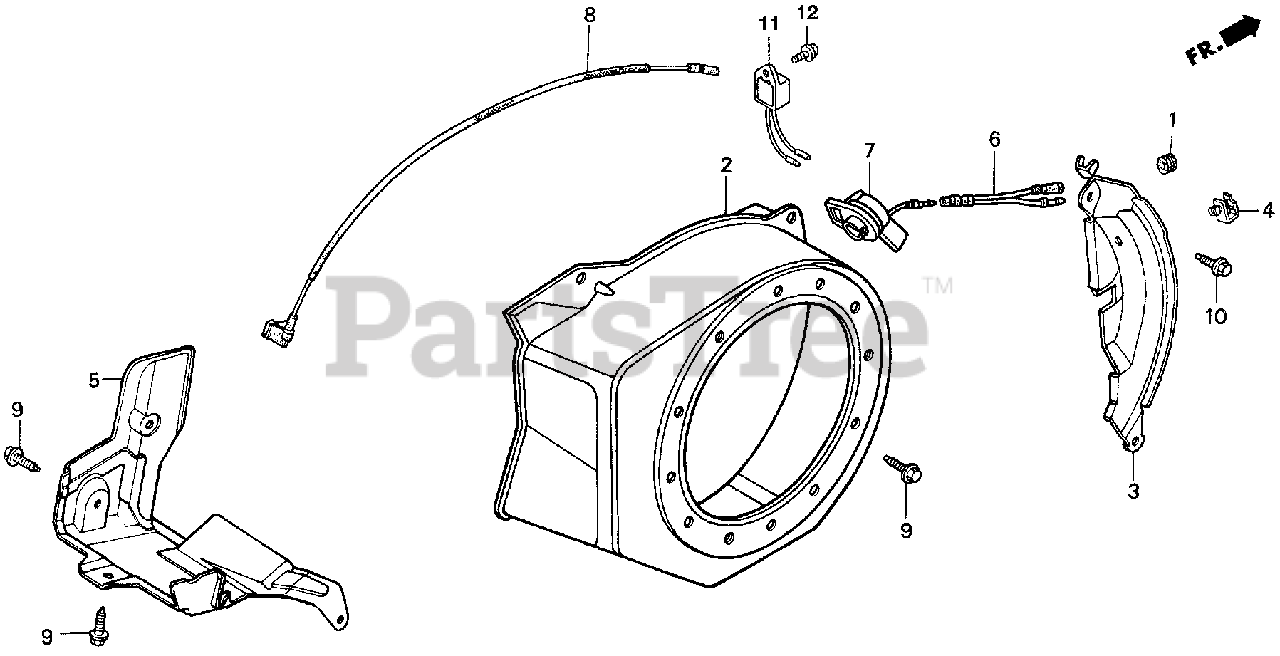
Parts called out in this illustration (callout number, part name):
1	GROMMET, ADJUSTING COVER
2	COVER, FAN *NH1* (BLACK)
3	PLATE, SIDE (ALERT & LAMP)
3	PLATE, SIDE
4	CLAMP, CORD
4	CLIP, HARNESS
6	SUB-HARNESS
7	SWITCH ASSY., ENGINE STOP
8	WIRE, STOP SWITCH (370MM)
9	BOLT, FLANGE (6X12) (CT200)
10	BOLT, FLANGE (6X20) (CT200)
11	ALERT UNIT, OIL
12	BOLT, FLANGE (6X8)
